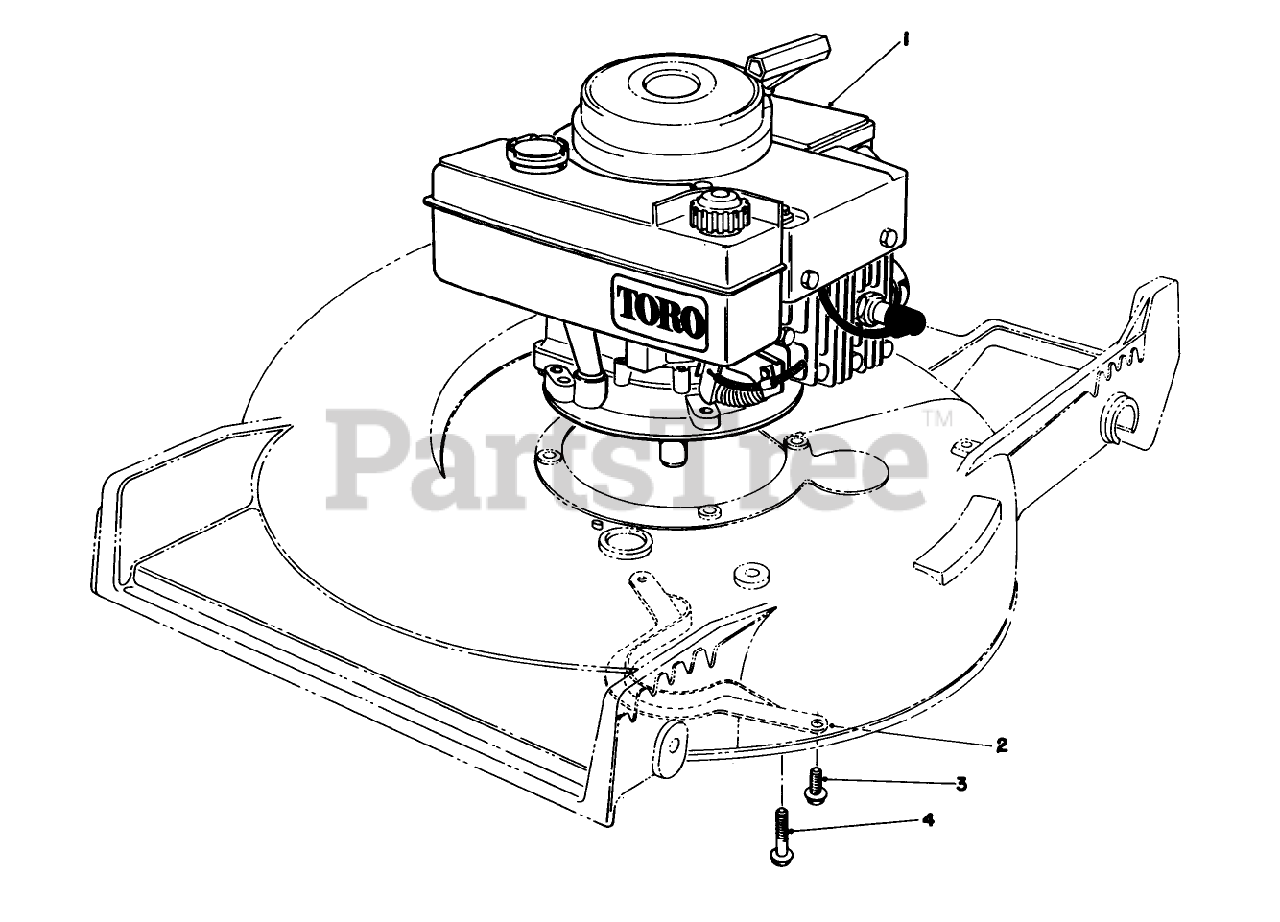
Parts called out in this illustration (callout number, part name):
1	Engine
3	SCREW-HWHTF
4	3/8-16 X 2 CAPSCREW
